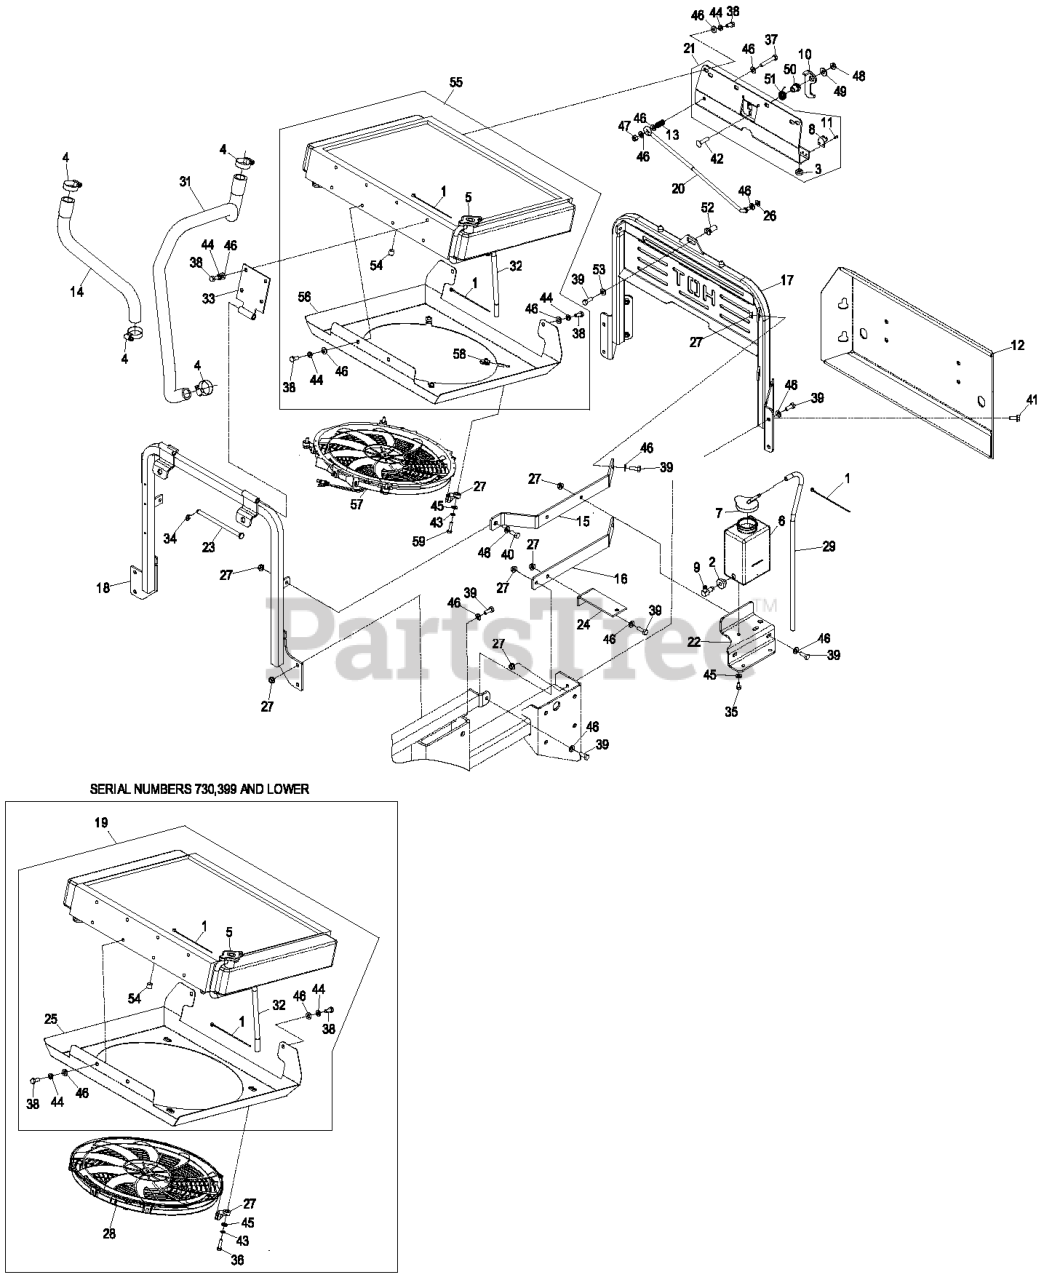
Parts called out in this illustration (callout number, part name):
1	TIE-CABLE
5	CAP-RADIATOR
6	TANK-OVERFLOW
7	CAP-TANK, OVERFLOW
10	HOOK,LATCH
12	WLD,REAR BUMPER
13	SPRING,LOCK PIN
14	HOSE,RADIATOR UPPER D902(
16	RIB, BOTTOM
17	WLD,REAR GUARD
18	ASM, RAD. MOUNT W/ DECALS
19	ASM,RADIATOR
20	ROD,PROP
21	ASM,LATCH PLATE S.O.
22	BRACKET,BOTTLE
24	BRACKET, HYDRAULIC TANK
25	SHROUD,FAN
28	KIT,16' FAN SERVICE
30	MOUNT,FAN
31	HOSE,RADIATOR LOWER D902
32	HOSE,OVERFLOW
33	WLD,HINGE PLATE
35	SCREW-HH
36	SCREW-HH
37	SCREW-HH
38	SCREW-HH
39	SCREW-HH
40	SCREW-HH
41	SCREW-HHF
42	SCREW-CARR
43	SCREW-HH
44	WASHER-LOCK
45	WASHER-FLAT
46	WASHER-PLAIN
47	NUT-LOCK, NI
49	WASHER-FLAT
50	BUSHING-LATCH, SEAT
51	SPRING,LATCH
52	PIN,LATCH
53	WASHER-SPRING
54	PLUG-PIPE
56	SHROUD,FAN
58	Nut, Retainer Panel
59	SCREW-HH
